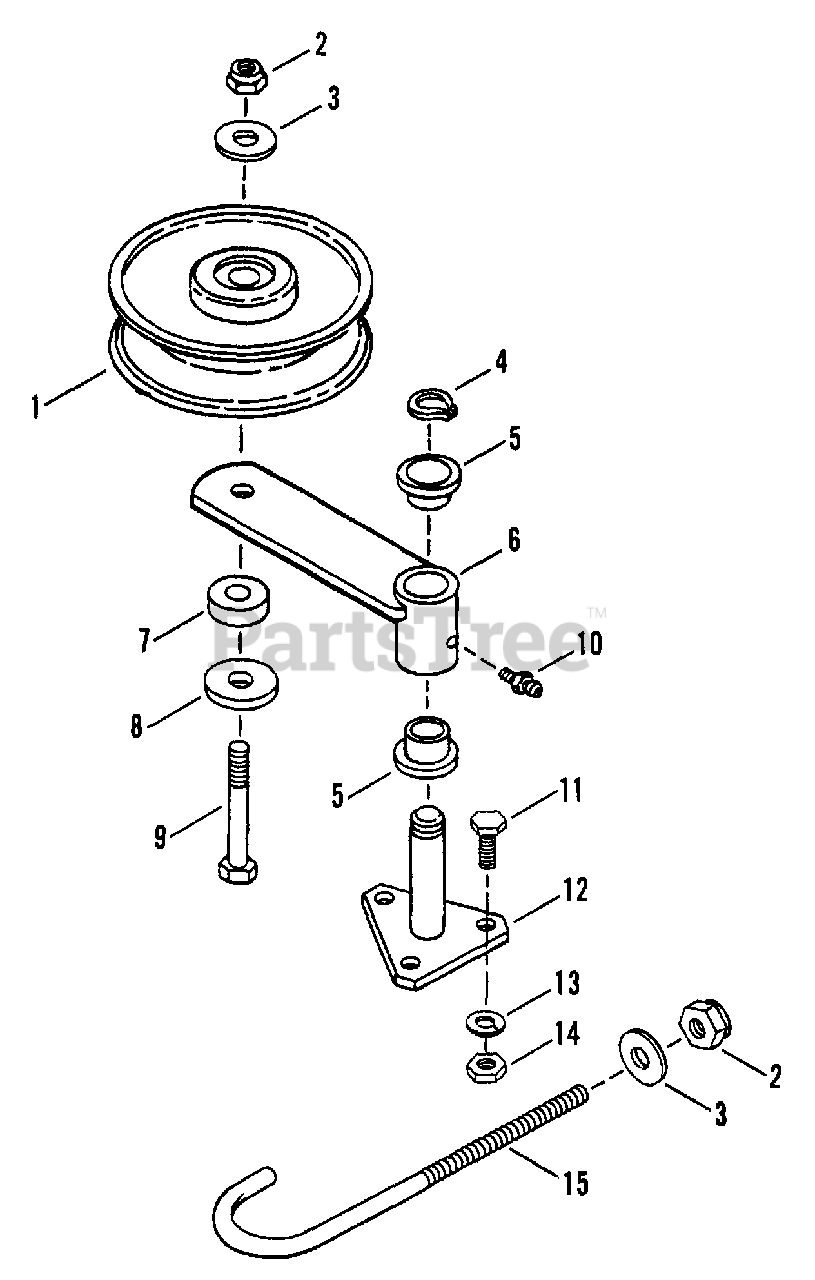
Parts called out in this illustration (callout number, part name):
1	PULLEY, Idler, V-Groove (5.00 O.D.)
2	NUT, 3/8-16 HEX NYLON LOCK
3	WASHER, 3/8" USS
4	RING, 1" Retaining
5	BUSHING
6	IDLER ARM (Weldment), 48" Blade/Blade Deck
7	BUSHING, .38" I.D. x 1" O.D. x .410"
8	WASHER, 13/32" Flat
9	BOLT, 3/8-16 x 2-1/2" Hex Head Cap, Grade 8
10	FITTING, Lube
11	BOLT, 3/8-16 X 1" GD5 CZ
12	PIVOT, Idler Arm
13	WASHER, 3/8" SPLIT LOCK
14	NUT, 3/8-16 Hex, Grade 5
15	HOOK, "J"
